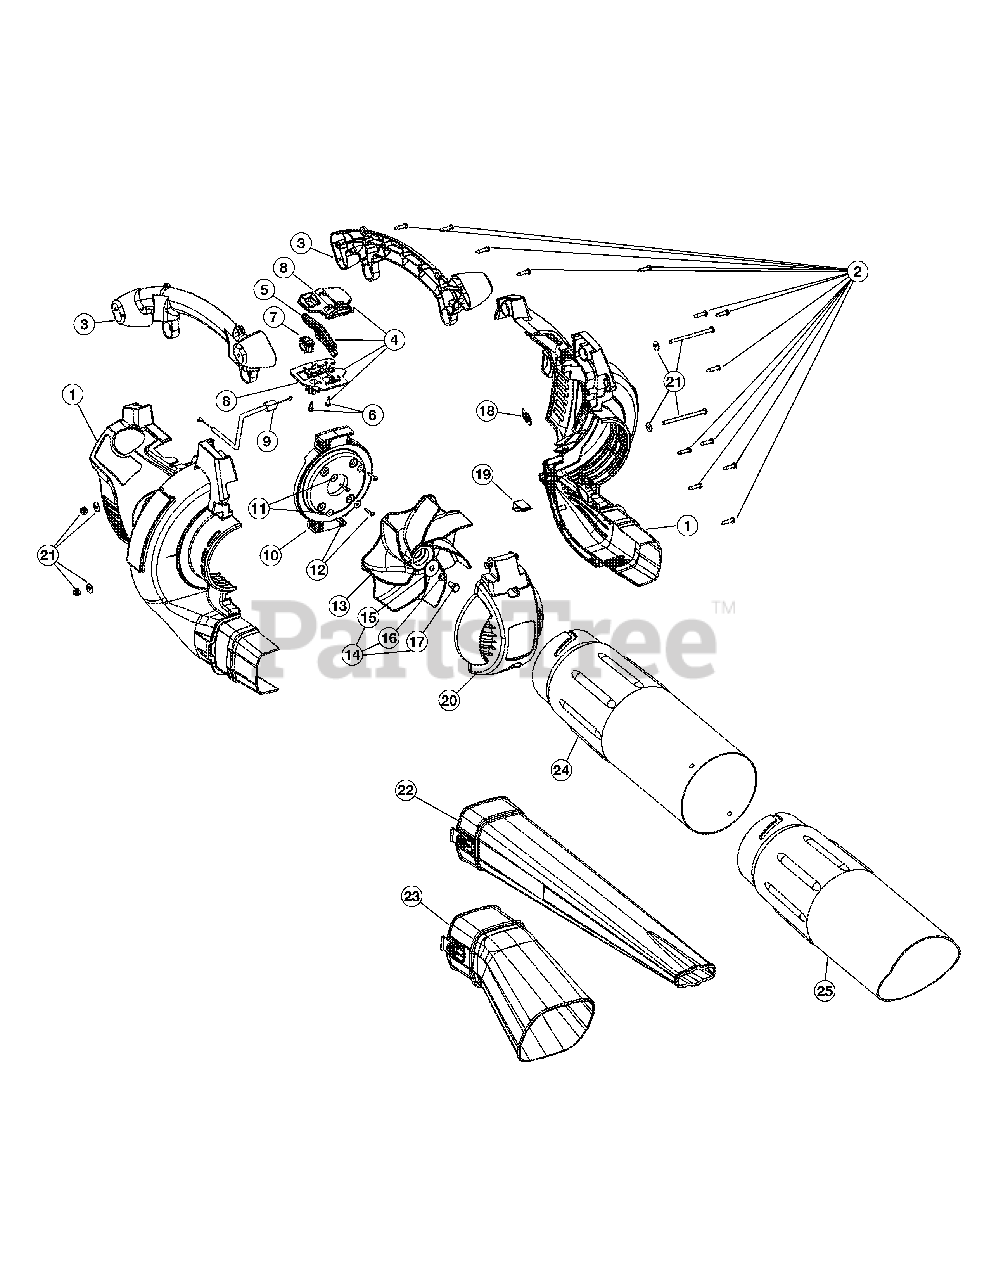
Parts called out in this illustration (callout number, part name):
1	Engine Cover Assembly
3	Handle Assembly
4	Throttle Control Assembly
5	Throttle Control Lever
7	Rocker Switch Assembly
8	Throttle Control Plate
9	Throttle Cable
10	Engine Mount Plate
12	Screw
13	Impeller Blade
14	Impeller Hardware
15	Washer
16	Lock Washer
18	Vacuum Door Spring
19	Vacuum Door Lock
20	Vacuum Door
21	Mounting Plate Hardware
22	Blower Tube
23	Vacuum Bag Adapter
24	Upper Vacuum Tube
25	Lower Vacuum Tube
